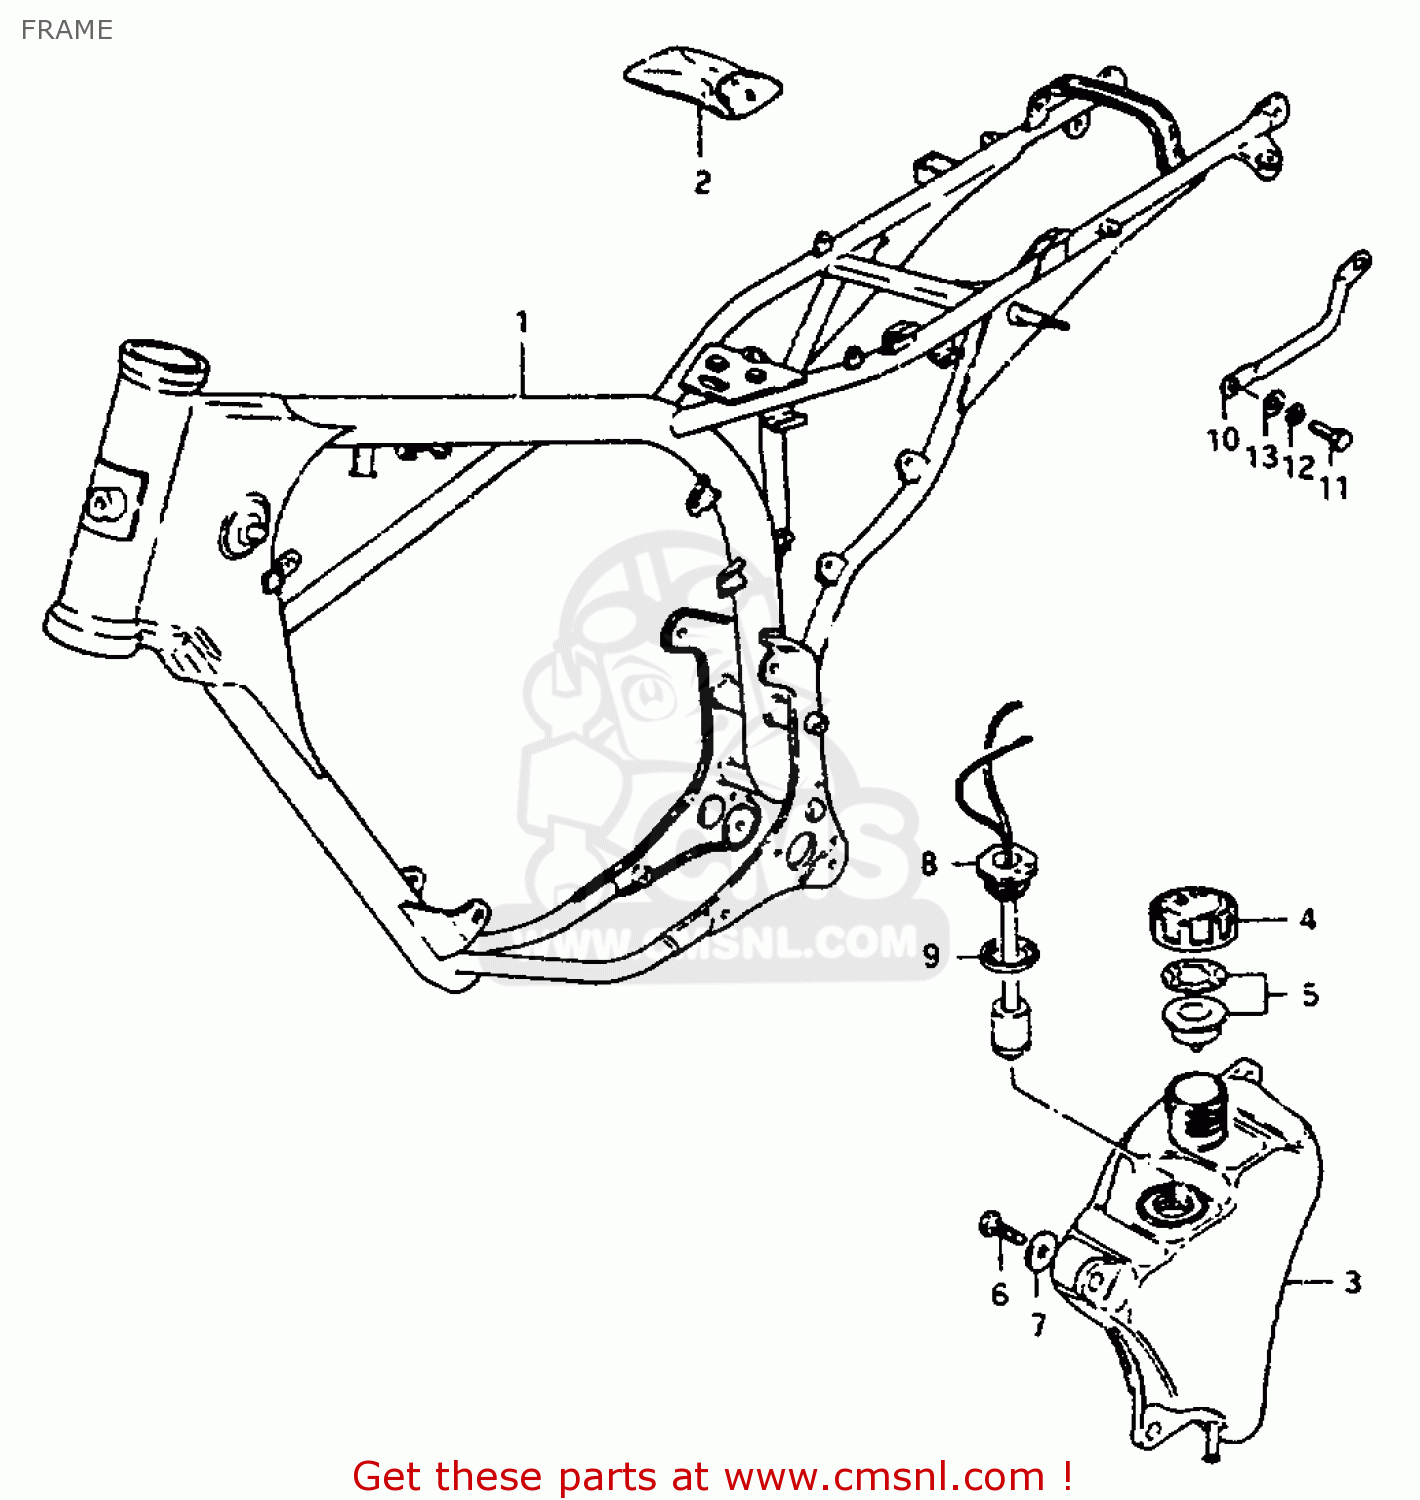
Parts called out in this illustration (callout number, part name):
1	FRAME (BLACK)
2	TOOL SET
3	TANK, OIL
4	CAP,OIL TANK
5	GASKET SET (NAS)
6	BOLT, UPPER
7	WASHER
8	SWITCH, OIL LEVEL
9	GASKET (NAS)
10	GRIP, STAND
11	BOLT
12	LOCK WASHER
13	WASHER
